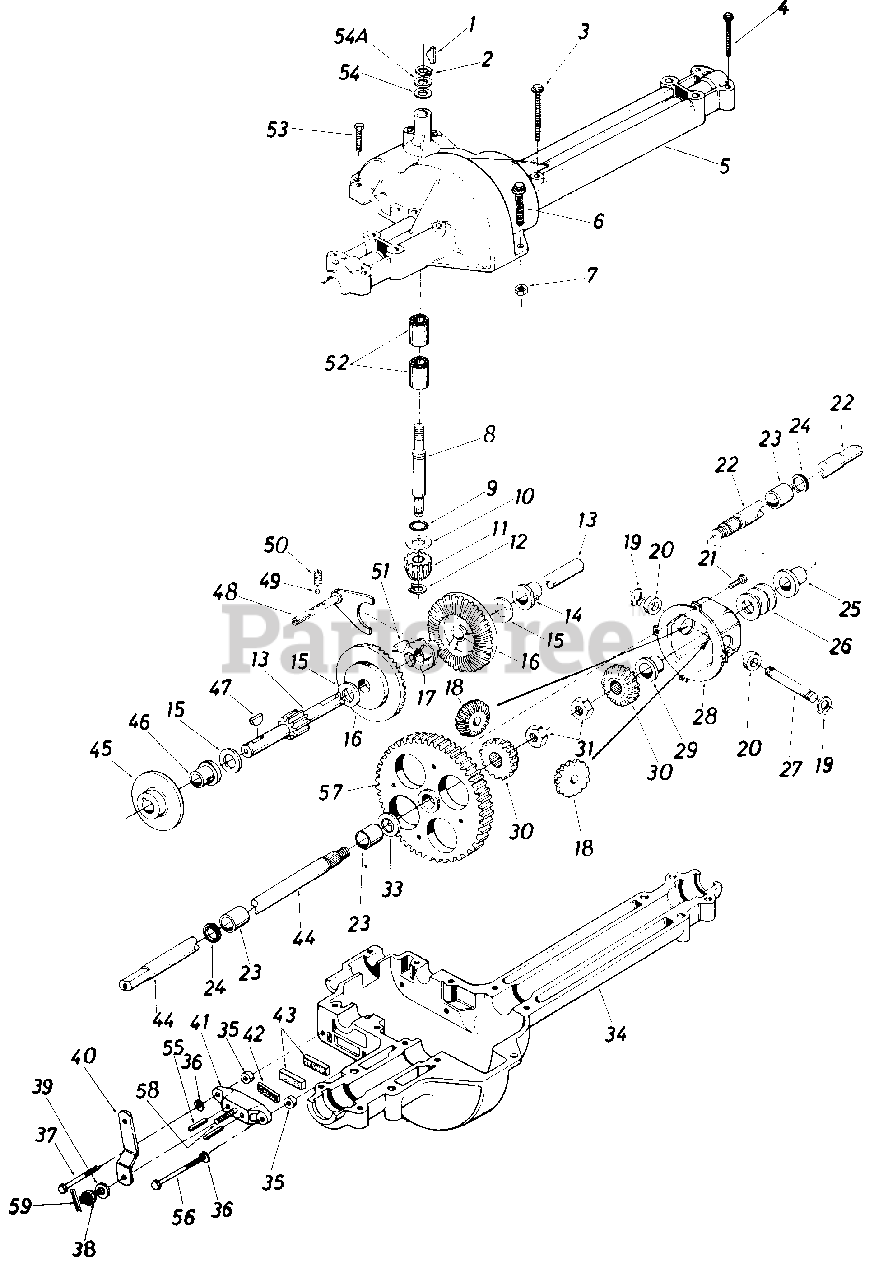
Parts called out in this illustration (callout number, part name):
1	#4 Hi-Pro Key 3/32 x 5/8" Dia.
2	Snap Ring .625" Shaft
3	Hex Bolt 1/4-20 x 1.75" Lg.*
4	Hex Bolt 1/4-20 x 1.25" Lg.
5	Upper Housing
6	Hex Fl-Bolt 1/4-20 x .88" Lg.
7	Hex Nut 1/4-20 Thd.
8	Input Shaft
9	Square Seal 5/8" I.D.
10	Thrust Washer 5/8" I.D. x 1.25" O.D.
11	Pinion Input 14T
12	Retaining Ring 7/16" Ext.
13	Drive Shaft
14	Flange Brg. 5/8" I.D. x 3/4" Lg.
15	Fl-Wash.
16	Bevel Gear 42T
17	Clutch Collar
18	Miter Gear 15T
19	Snap Ring
20	Thrust Bearing 1/2" I.D. x 1.0" O.D.
21	Pan Head Scr. 1/4-20 x .50" Lg. w/Patch
22	Axle R.H. Kit
23	Sleeve Bearing 3/4" I.D. x 1.0" Lg.
24	Oil Seal 3/4" I.D.
25	Flange Bearing 3/4" I.D. x 15/16" Lg.
26	Fl-Wash. .760" I.D. x 1.49" O.D.
27	Cross Shaft
28	Differential Housing Ass'y.
30	Miter Gear
31	Retaining Ring
33	Fl Wash. .760" I.D. x 1.49" O.D.
34	Lower Housing
35	Spacer .53" O.D. x 3/8" Lg.
36	L-Wash. 1/4" I.D.
37	Hex Bolt 1/4-20 x 1.50" Lg. (Grade 5)
38	Castle Nut 5/16-24 Thd.
39	Fl-Wash. .344" I.D. x .875" O.D.
40	Actuating Arm
41	Brake Yoke
42	Puck Plate
43	Brake Puck
44	Axle L.H. Kit
45	Brake Disc
46	Flange Bearing 5/8" I.D. x 15/16" Lg.
47	Woodruff Key 3/16 x 5/8 HT
48	Shift Fork Ass'y.
49	Ball Detent .250" Dia.
50	Spring Detent
51	#9 Hi-Pro Key 3/16" x 3/4" Dia. HT
52	Needle Brg. 5/8" I.D. x 1/2" Lg.
53	Hex Bolt 1/4-20 x 1.00" Lg.
54	Fl-Wash. 5/8" I.D. x .030
54A	Fl-Wash. 5/8" I.D. x .040
55	Actuating Pin 5/16" Dia.
56	Hex Bolt 1/4-20 x 1.50" Lg. (Grade 5)
57	Differential Gear 72T Ass'y. w/ Beari ng
58	Sq. Hd. Bolt 5/16-24 Thd.
59	Hex Jam Nut 5/16-24 Thd.
